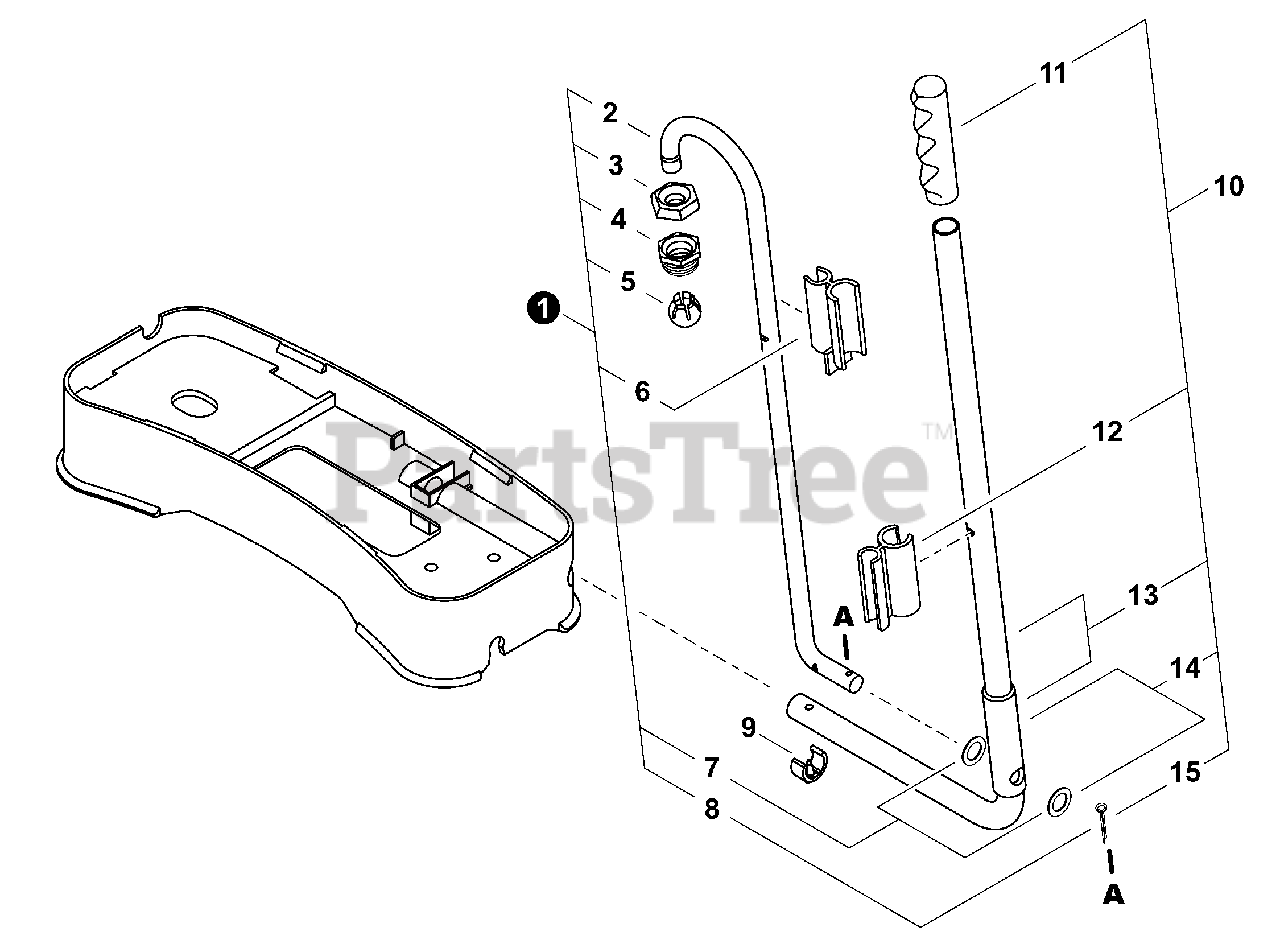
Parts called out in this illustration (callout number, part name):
1	PUMP ARM KIT
2	ARM, PUMP
3	BOOT, JOINT
4	NUT, JOINT
5	JOINT, BALL
6	CLIP, PUMP LEVER
7	WASHER
8	PIN, COTTER
9	C-CLIP
10	LEVER KIT, PUMP
11	GRIP, LEVER
12	CLIP, WAND
13	LEVER, PUMP
14	WASHER
15	PIN, COTTER
